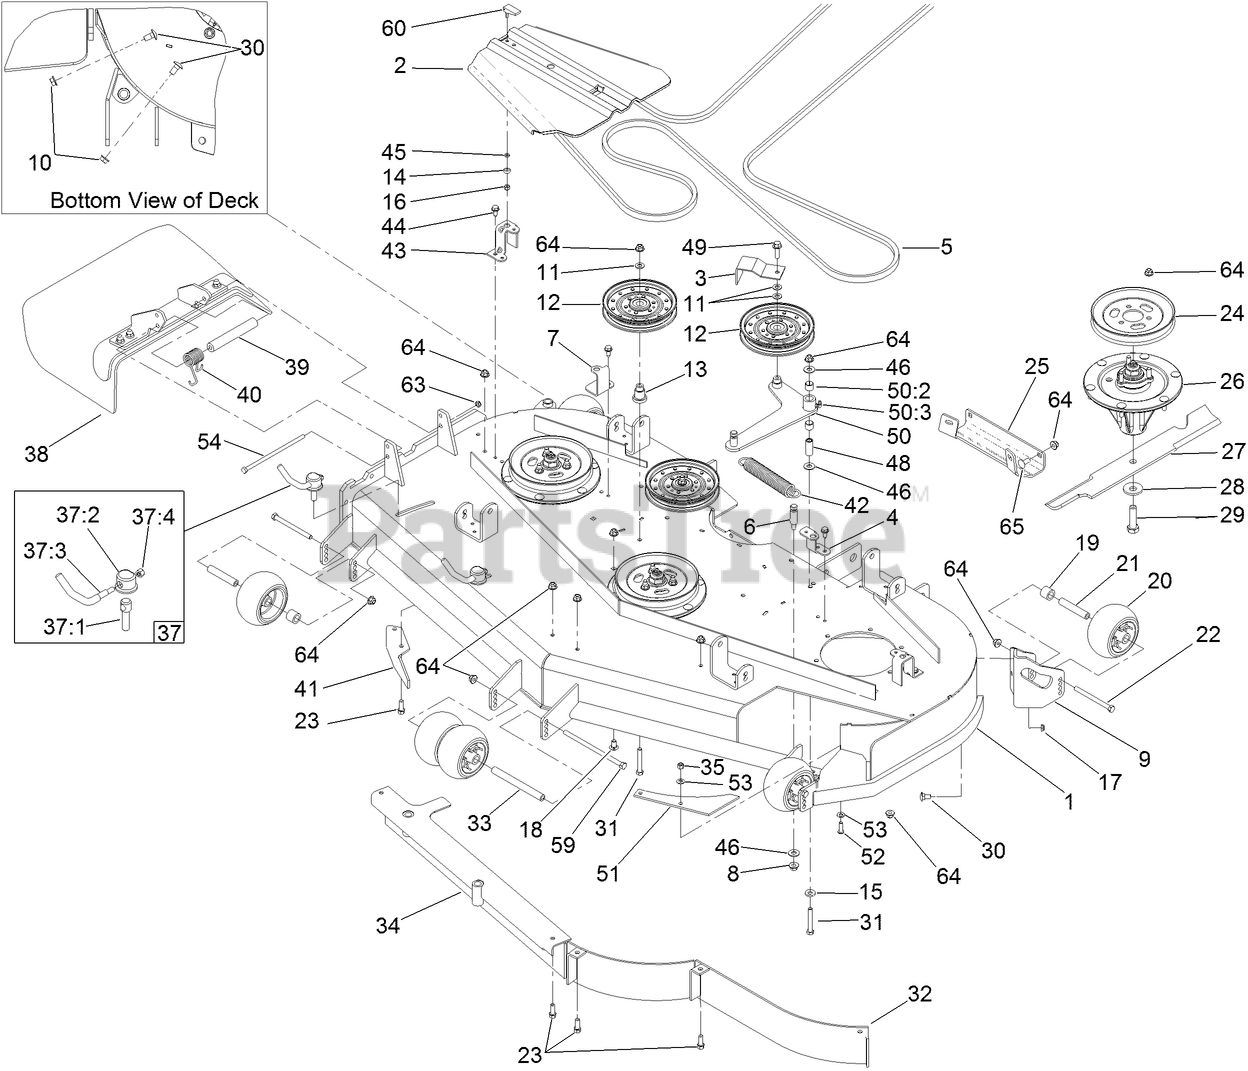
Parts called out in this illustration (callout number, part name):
1	DECK DECAL ASM
2	COVER-BELT
3	GUIDE-BELT
4	BRACKET-COVER, TALL
5	BELT-V
6	PIN-THREADED, SPRING ANCHOR
7	BRACKET-COVER
8	NUT-HF
9	MOUNT-WHEEL, LH
10	NUT-HHF, WHIZ
11	WASHER-FLAT
12	IDLER-PULLEY, FLAT
13	MOUNT-PULLEY
14	BUSHING-LATCH, SWELL
15	WASHER-BELLEVILLE
16	NUT-LOCK, HH
17	NUT-LOCK, NI
18	SCREW-CARR
19	TUBE-SPACER
20	ROLLER-SCALP, ANTI
21	TUBE-SPANNER
22	SCREW-HH
23	SCREW-HWH
24	Pulley
25	Plate-Skid
26	SPINDLE ASM
27	BLADE-HI FLOW
28	Washer-Blade Bolt, Heavy
29	SCREW-BLADE
30	SCREW-CARR
31	SCREW-HH
33	SPACER-WHEEL
35	NUT-LOCK, NI
37	LEVER ASM
37:1	Screw-Lock
37:2	CAP-LOCK
37:3	Lever-Lock
37:4	NUT-LOCK, NI
38	RUBBER DEFLECTOR ASM
39	SPACER
40	SPRING-TORSION
41	BAFFLE-DISCHARGE
42	SPRING-EXTENSION
43	BRACKET-COVER
44	SCREW-HWHTF
45	WASHER
46	WASHER-FLAT
48	BUSHING
49	SCREW-HHF
50	DECK IDLER ARM ASM
50:2	SLEEVE-BEARING
50:3	FITTING-GREASE, 90 DEG
51	PLATE-TURBO
52	SCREW-HSBH
53	WASHER-SPRING
54	SCREW-HH
59	SCREW-HH
60	HANDLE-LATCH, SWELL
63	NUT-LOCK, NI
64	NUT-HF, NI
65	SCREW-CARR
